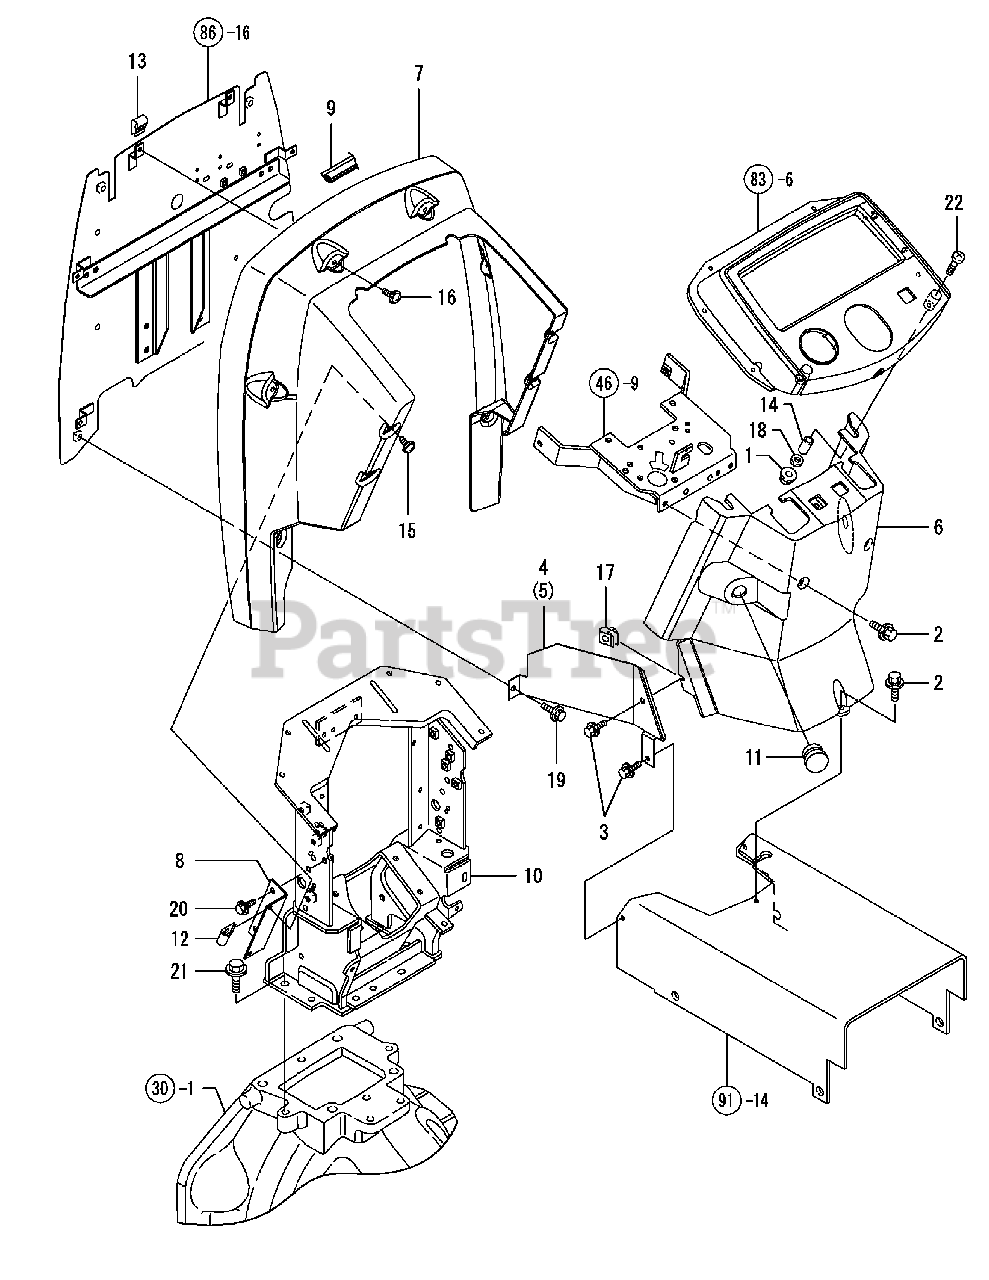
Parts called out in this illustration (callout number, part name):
1	NUT W/WASHER 6
4	LOWER COVER L.H. CMP
5	LOWER COVER R.H. CMP
7	COVER,DASHBOARD
8	SUPPORT,DASHBOARD
9	WEATHER STRIP, 1700
10	SUPPORT,INSTRUMENT
12	NUT 5008
13	NUT 5008
14	COLLAR 10.5X17
15	SCREW 5X16
16	SCREW 5X16
19	BOLT M 8X 12 PLATED
20	BOLT M 8X 16 PLATED
21	BOLT M10X 20 PLATED
